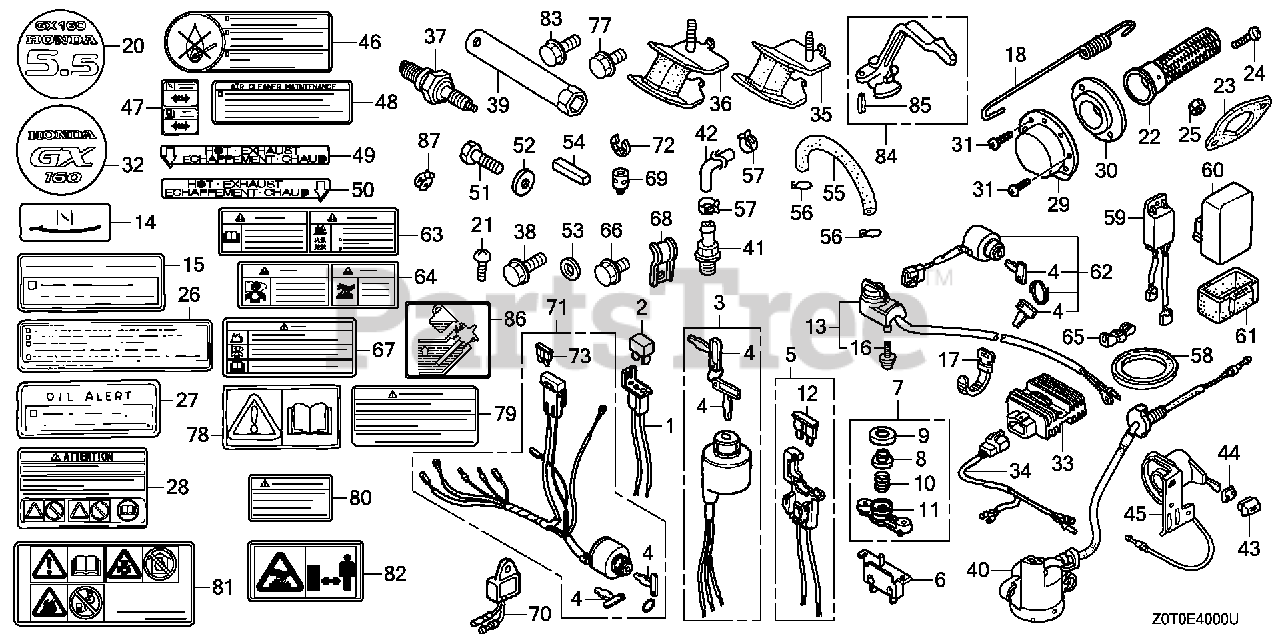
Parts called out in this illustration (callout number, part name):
54	KEY (4.78X4.78X38)
79	MARK, OPERATOR CAUTION (FRENCH)(MADE IN THAI)
80	MARK, EX. CAUTION (FRENCH)
